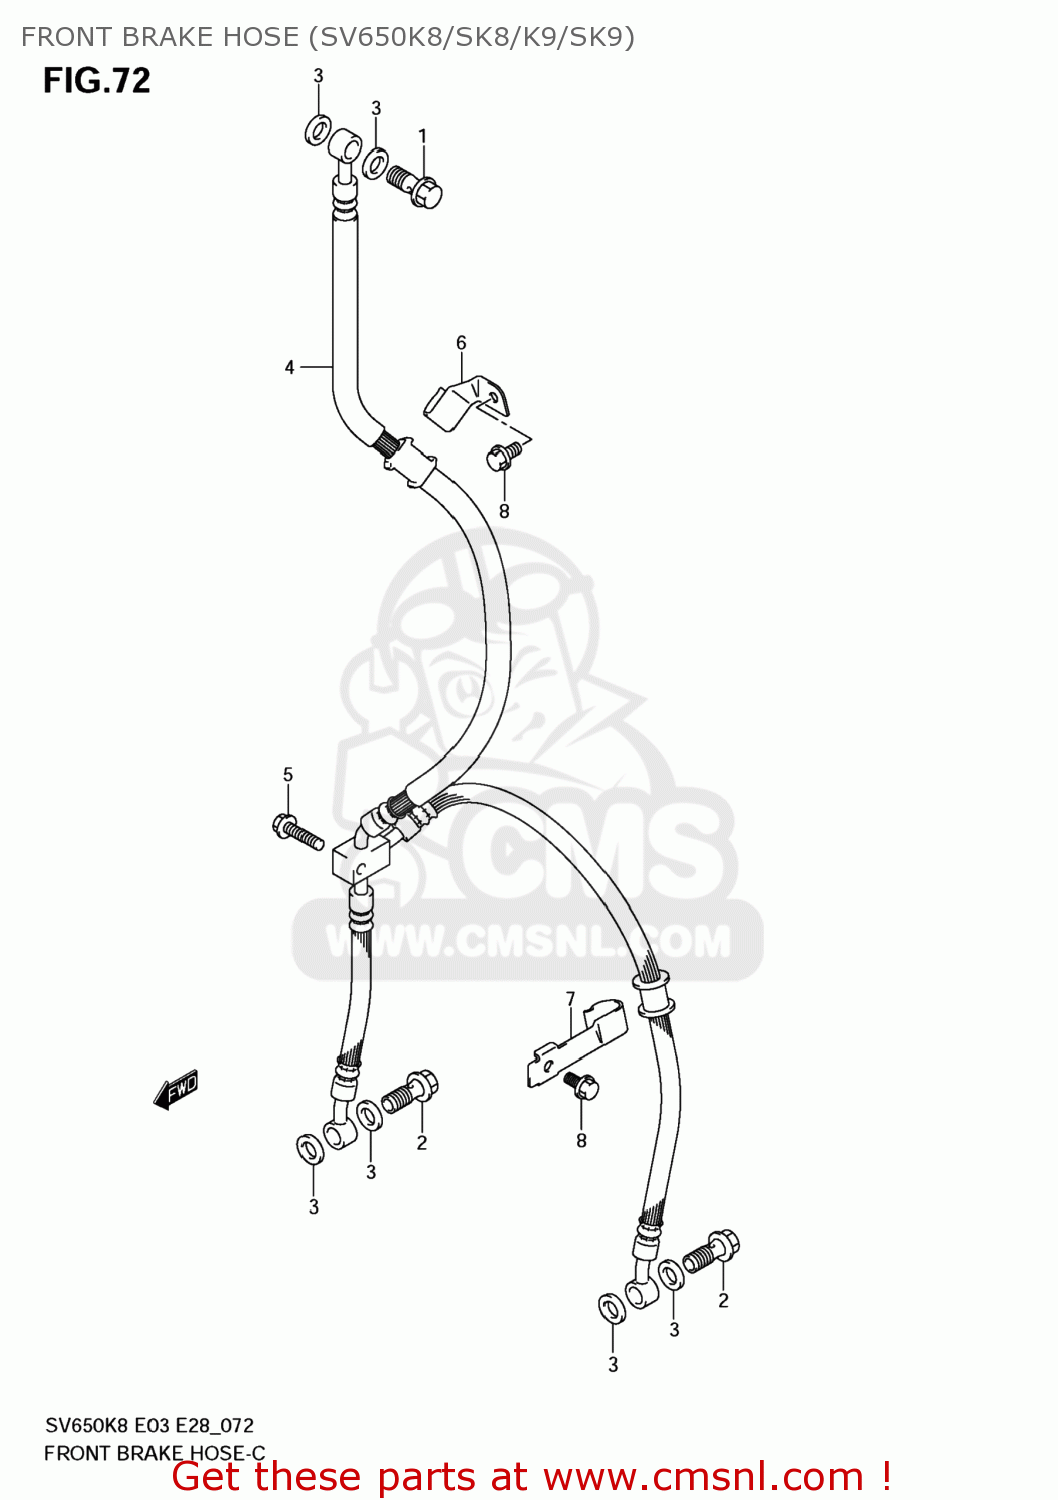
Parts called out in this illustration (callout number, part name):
1	BOLT UNION
2	BOLT UNION
3	WASHER(10X15X1.5)
4	HOSE,FR BRAKE
5	BOLT
6	CLAMP,FR BRAKE HOSE
7	CLAMP,FR BRAKE HOSE
8	BOLT
